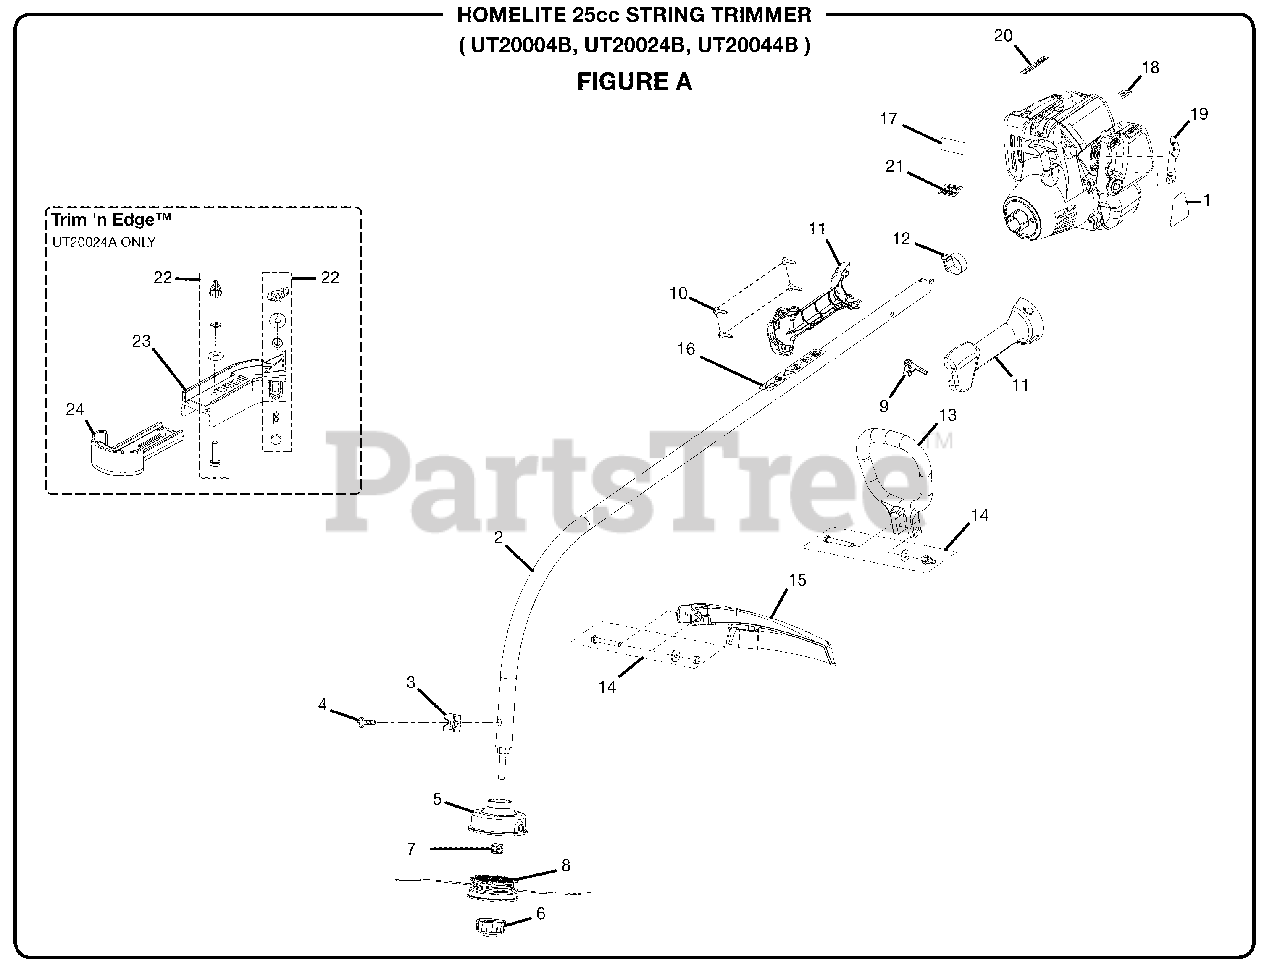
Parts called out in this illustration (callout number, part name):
1	STARTING INSTRUCTION DECAL
2	CURVED SHAFT ASSEMBLY
3	CLAMP
4	SCREW (10-32 x 3/8 in. )
5	HOUSING AND EYELET
6	SPOOL RETAINER (RH)
7	COMPRESSION SPRING
8	SPOOL W/LINE
9	TRIGGER
10	SCREW (10-14 x 7/8 in. TRUSS HD.)
11	HANDLE GRIP ASSEMBLY
12	BOOM CLAMP
13	FRONT HANDLE
14	FASTENER PARTS KIT
15	GRASS DEFLECTOR ASSEMBLY (UT20004B AND UT20024B)
16	DECAL, WARNING/STARTING BOOM
17	DECAL, TRIMLITE LOGO
18	DECAL, PRIMER
19	DECAL, CHOKE
20	DECAL, HOMELITE
21	LABEL, ZIP START
22	FASTENER PARTS KIT
23	EDGER BASE
24	EDGER GUIDE
